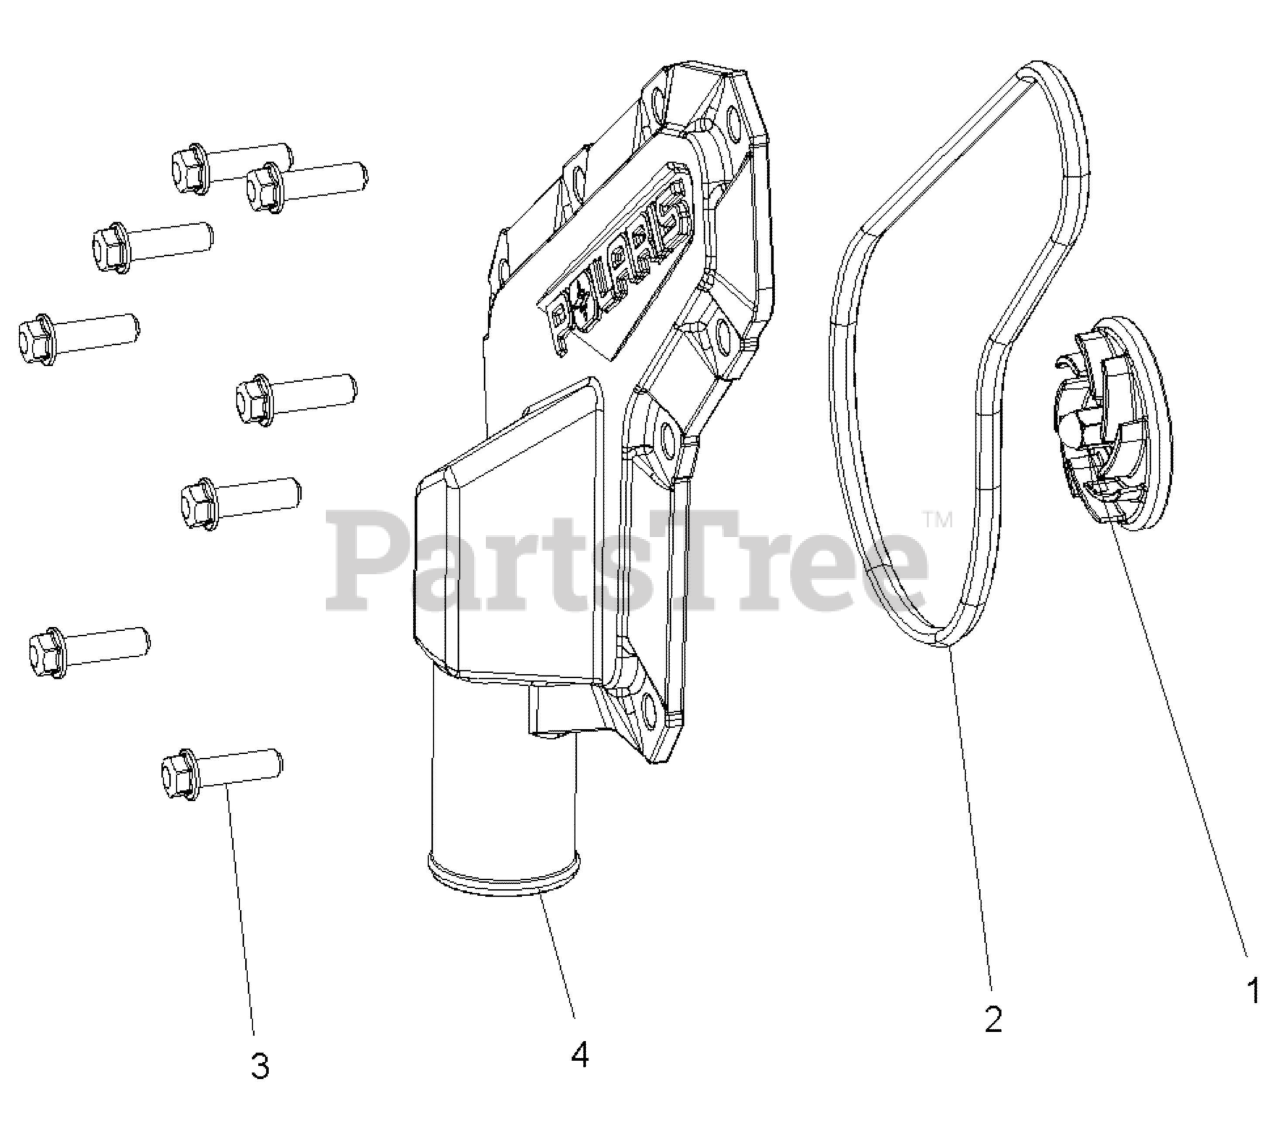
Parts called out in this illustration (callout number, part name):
1	IMPELLER-WATER PUMP 45MM,MACH
2	GASKET-WATERPUMP COVER
3	SCR-M6X20,HXFLG,0600214
4	COVER-WATERPUMP,CAST
